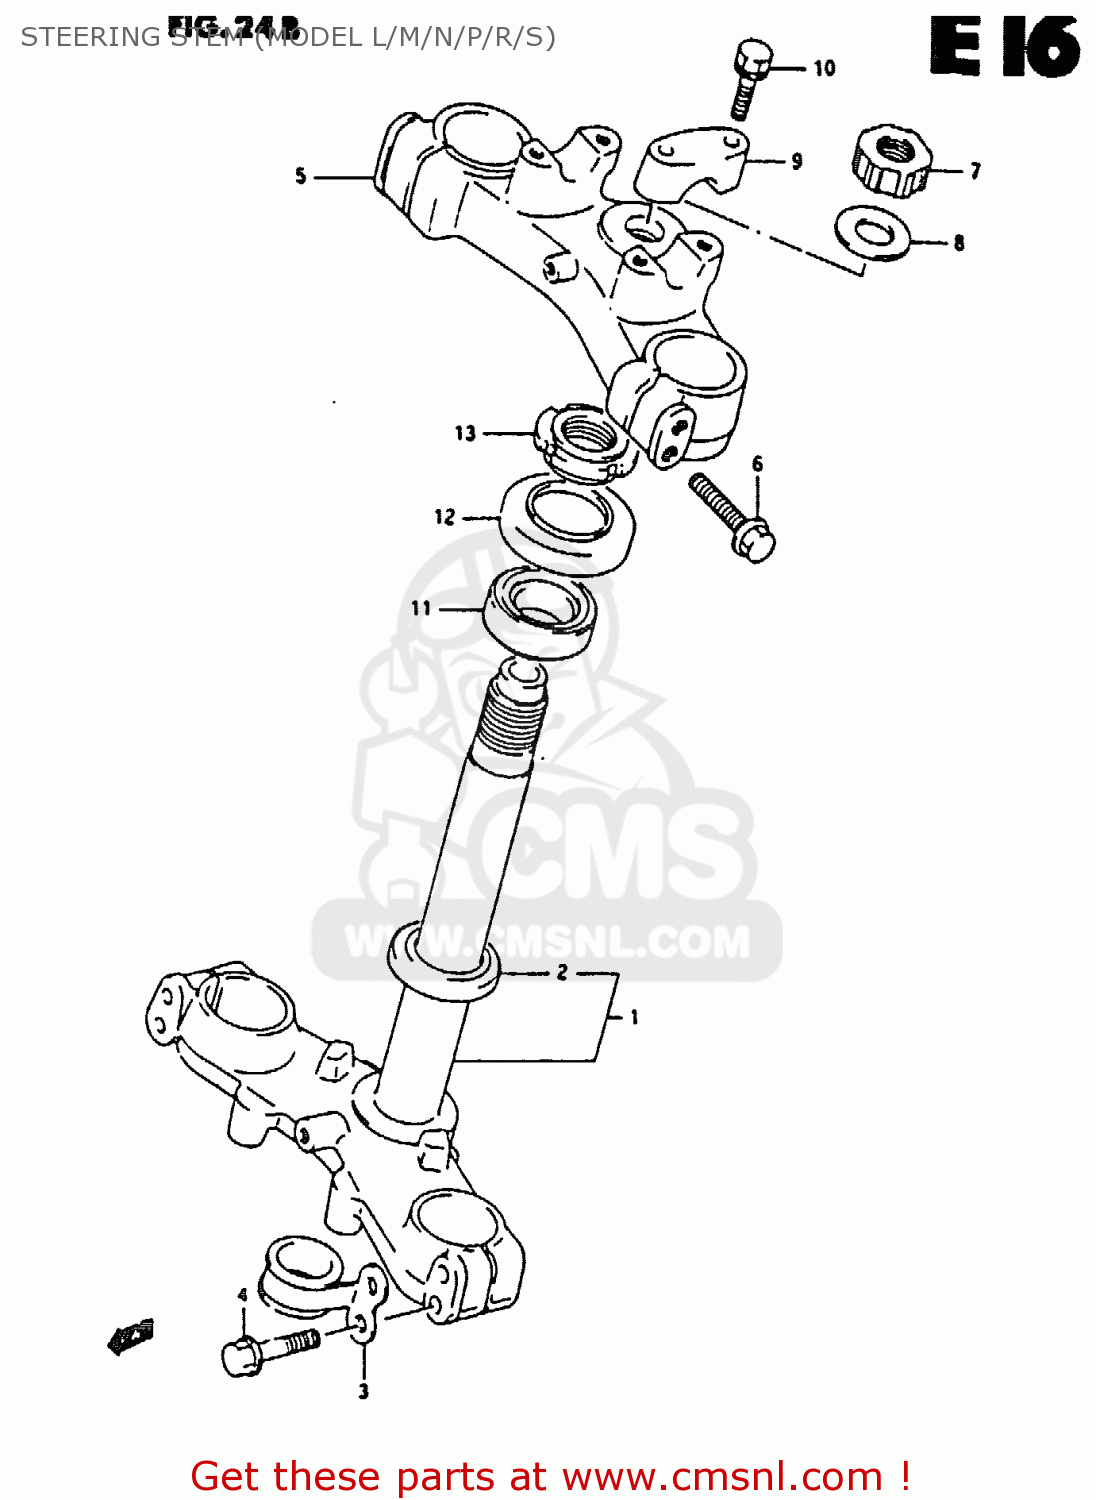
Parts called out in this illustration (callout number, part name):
1	STEM,STEERING
2	BEARING(26X47X15)
3	CLIP
4	BOLT
5	HEAD,STEERING STEM
6	BOLT
7	NUT,STEM HEAD
8	WASHER
9	HOLDER,HANDLEBAR
10	BOLT
11	TAPER,ROLLER BEARING
12	SEAL,STEERING UPR DUST
13	NUT,STEERING
